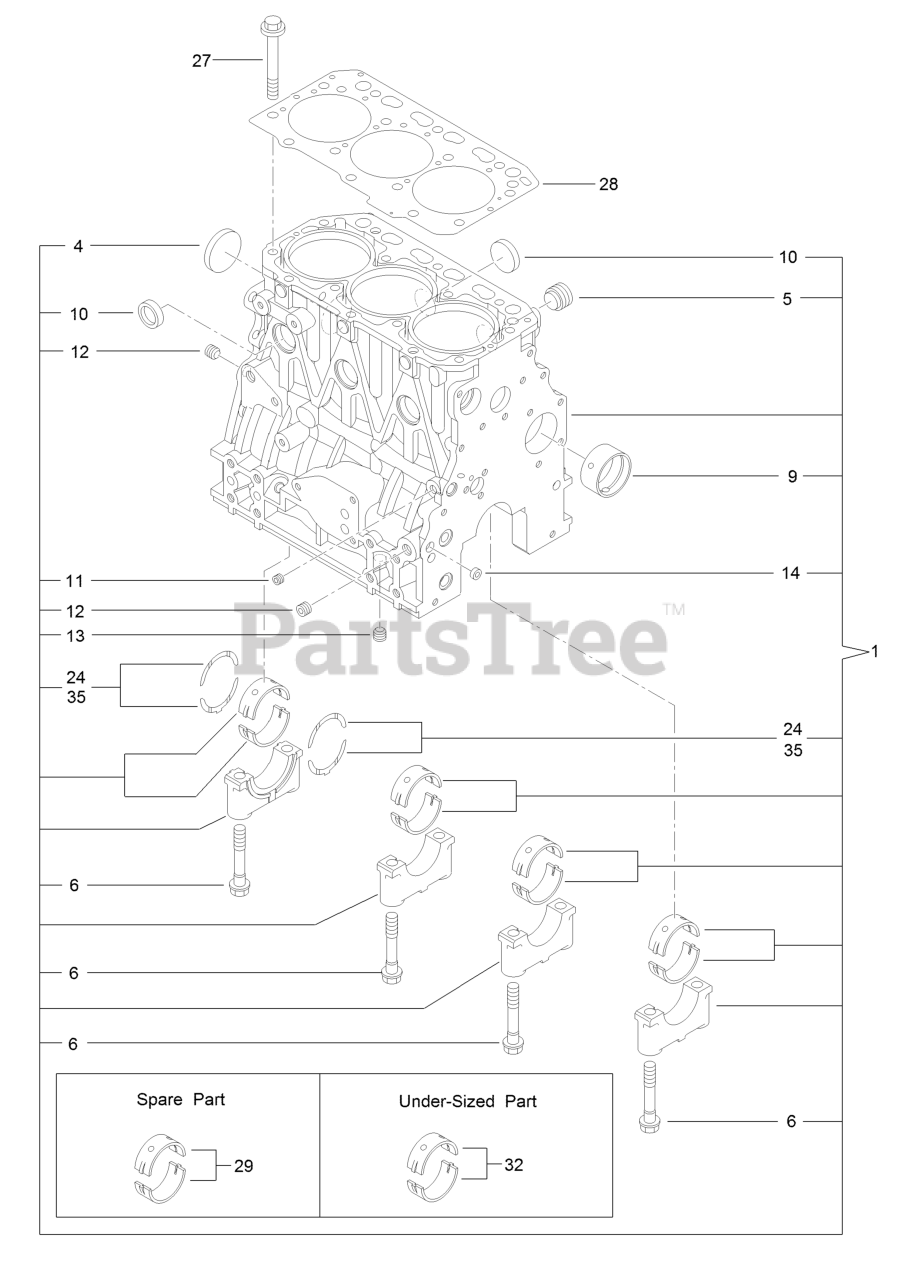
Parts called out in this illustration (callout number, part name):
1	Cylinder Block ASM
9	Bushing
24	Metal-Thrust
28	Head Gasket ASM
29	Metal-Main
32	Metal-Main (0.25)
35	Metal-Thrust (0.25)
